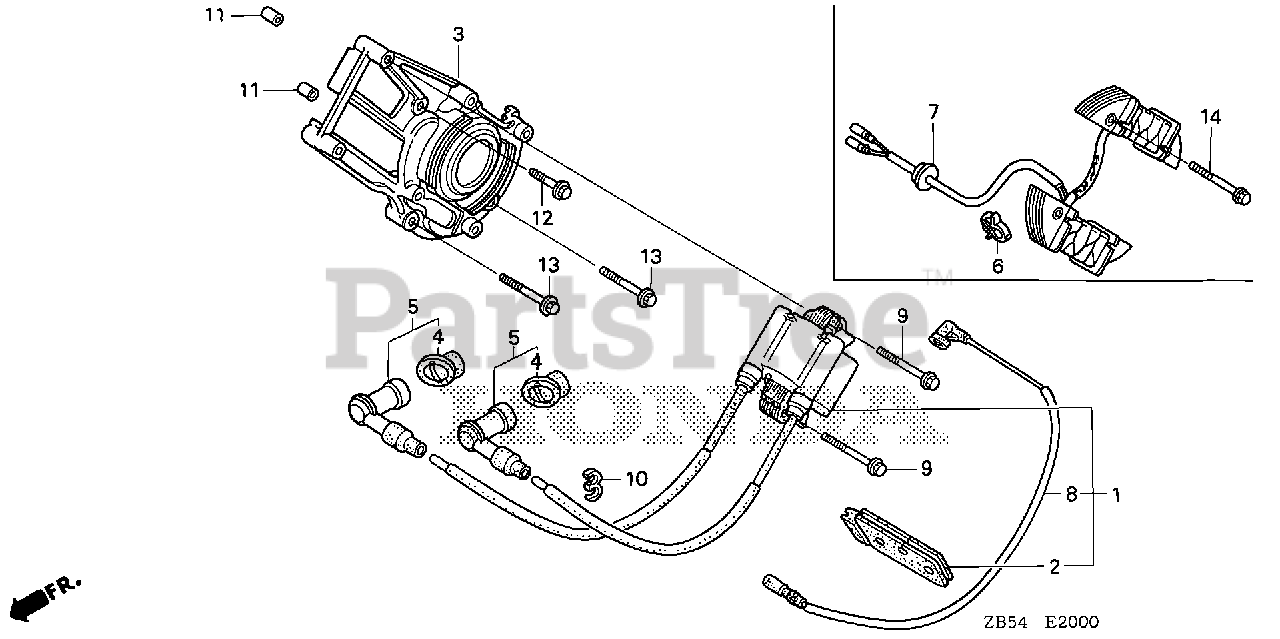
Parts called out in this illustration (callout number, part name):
1	COIL ASSY., IGNITION
2	GROMMET, IGNITION WIRE
3	STAY, IGNITION SYSTEM
4	SEAL, IGNITION
5	CAP ASSY., NOISE SUPPRESSOR
6	CLIP, IGNITION WIRE (8MM)
7	COIL ASSY., CHARGE (7.5A-10.5A)
8	WIRE, ENGINE STOP
9	BOLT, FLANGE (6X28) (CT200)
10	CLIP, HIGH TENSION CORD
11	PIN, DOWEL (8X10)
12	BOLT, FLANGE (6X22)
13	BOLT, FLANGE (6X28)
14	BOLT, FLANGE (6X32)
